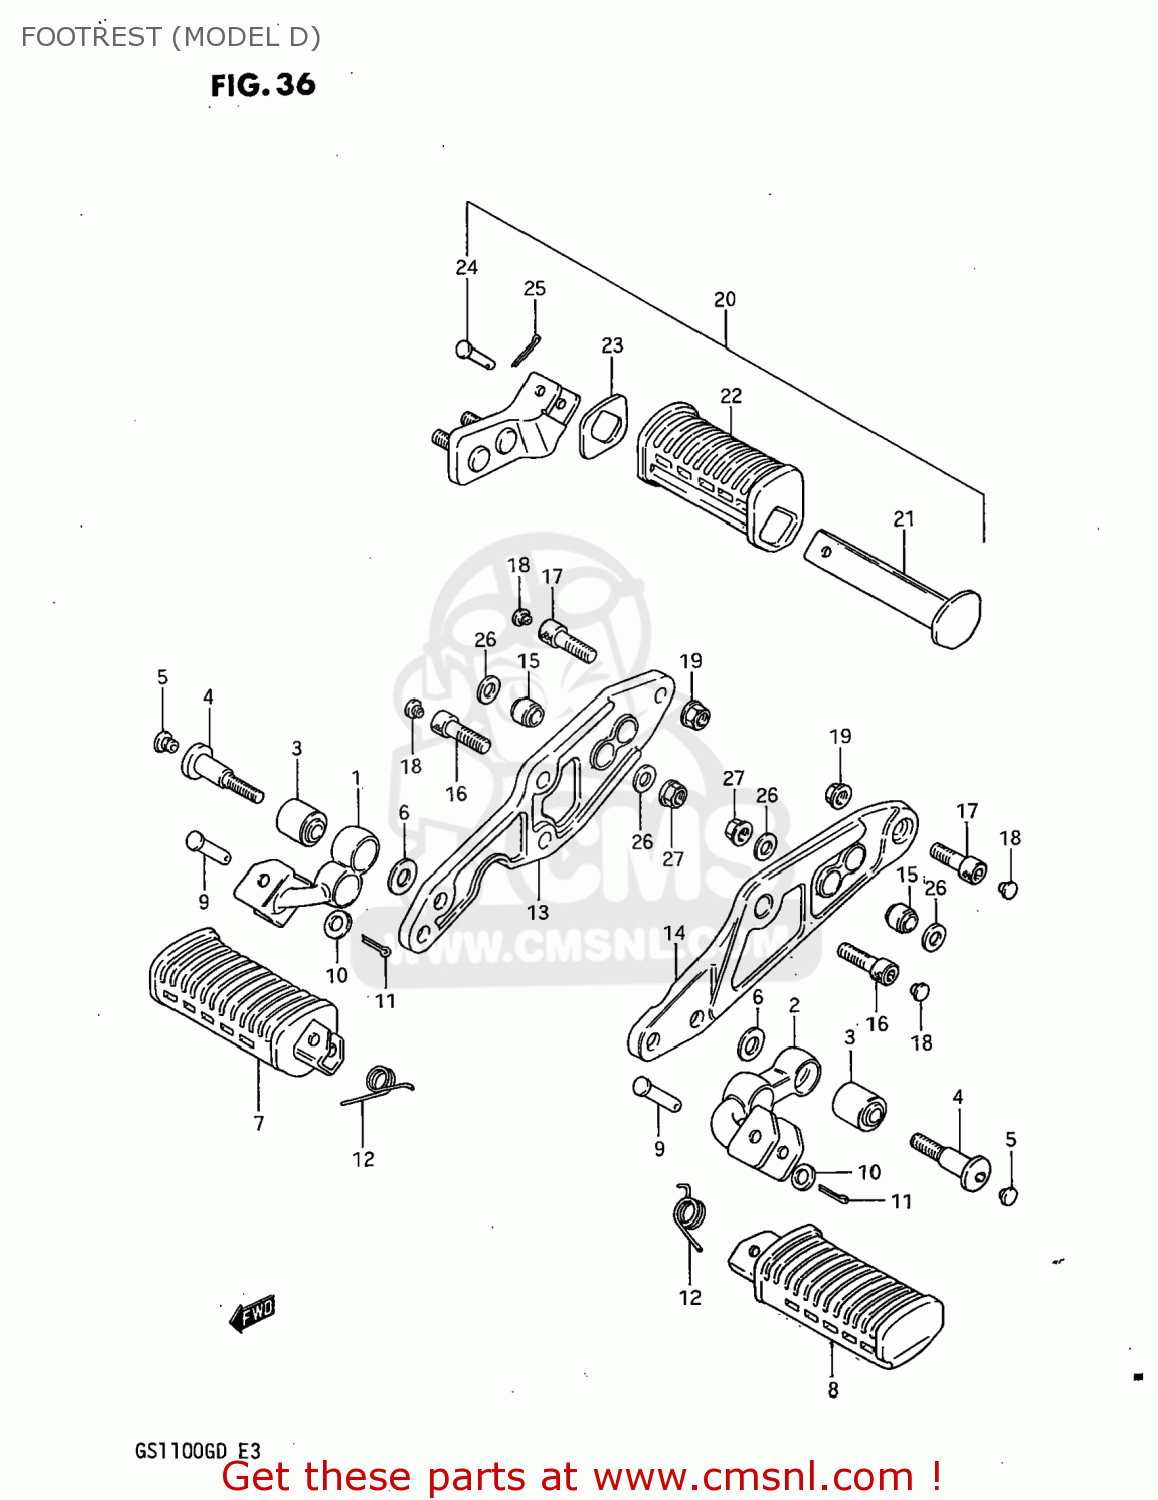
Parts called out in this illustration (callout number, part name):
1	BAR,FRONT FOOTREST,RIGHT
2	BAR,FRONT FOOTREST,LEFT
3	BUSH
4	BOLT(10X50)
5	CAP
6	WASHER (10X18X3.2)
7	RUBBER,FRONT FOOTREST
8	FOOTREST
9	PIN
10	WASHER
11	PIN 20X20
12	SPRING
13	BRACKET,MUFFLER,RIGHT
14	BRACKET,MUFFLER,LEFT
15	BUSH
16	BOLT
17	BOLT
18	CAP
19	NUT
20	FOOTREST ASSEMBLY,REAR
21	BAR,REAR FOOTREST
22	RUBBER,REAR FOOTREST
23	WASHER,REAR FOOTREST RUBBER
24	PIN
25	PIN 20X20
26	WASHER(10.5X20X3.2)
27	NUT
